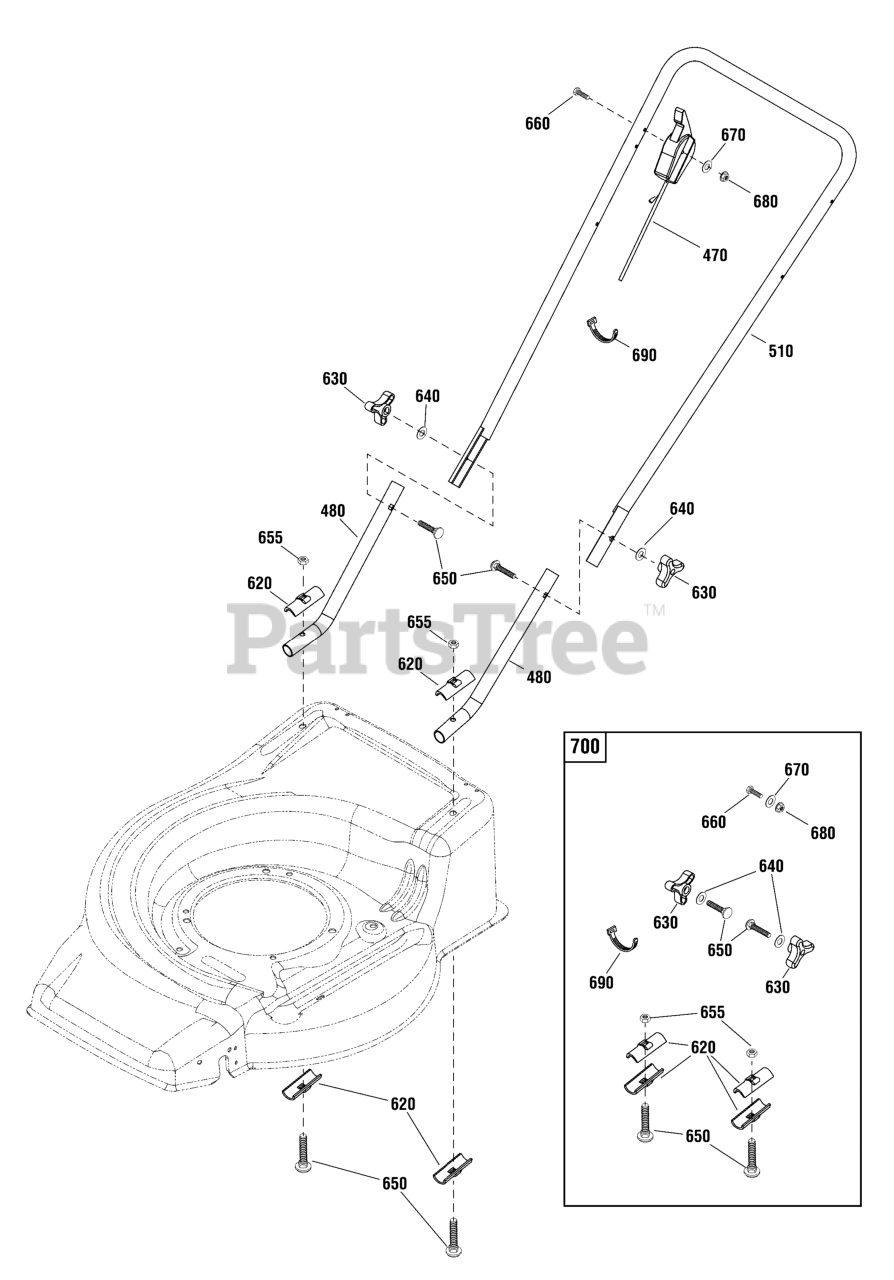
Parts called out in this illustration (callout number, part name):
470	THROTTLE CONTROL
480	HANDLE, Lower
510	HANDLE, Upper
620	* SADDLE PLATE
630	* KNOB, Handle
660	* BOLT, Throttle Control
670	* WASHER, Throttle Control
680	* NUT, Throttle Control
690	* CABLE TIE
700	KIT, Hardware, Handle
